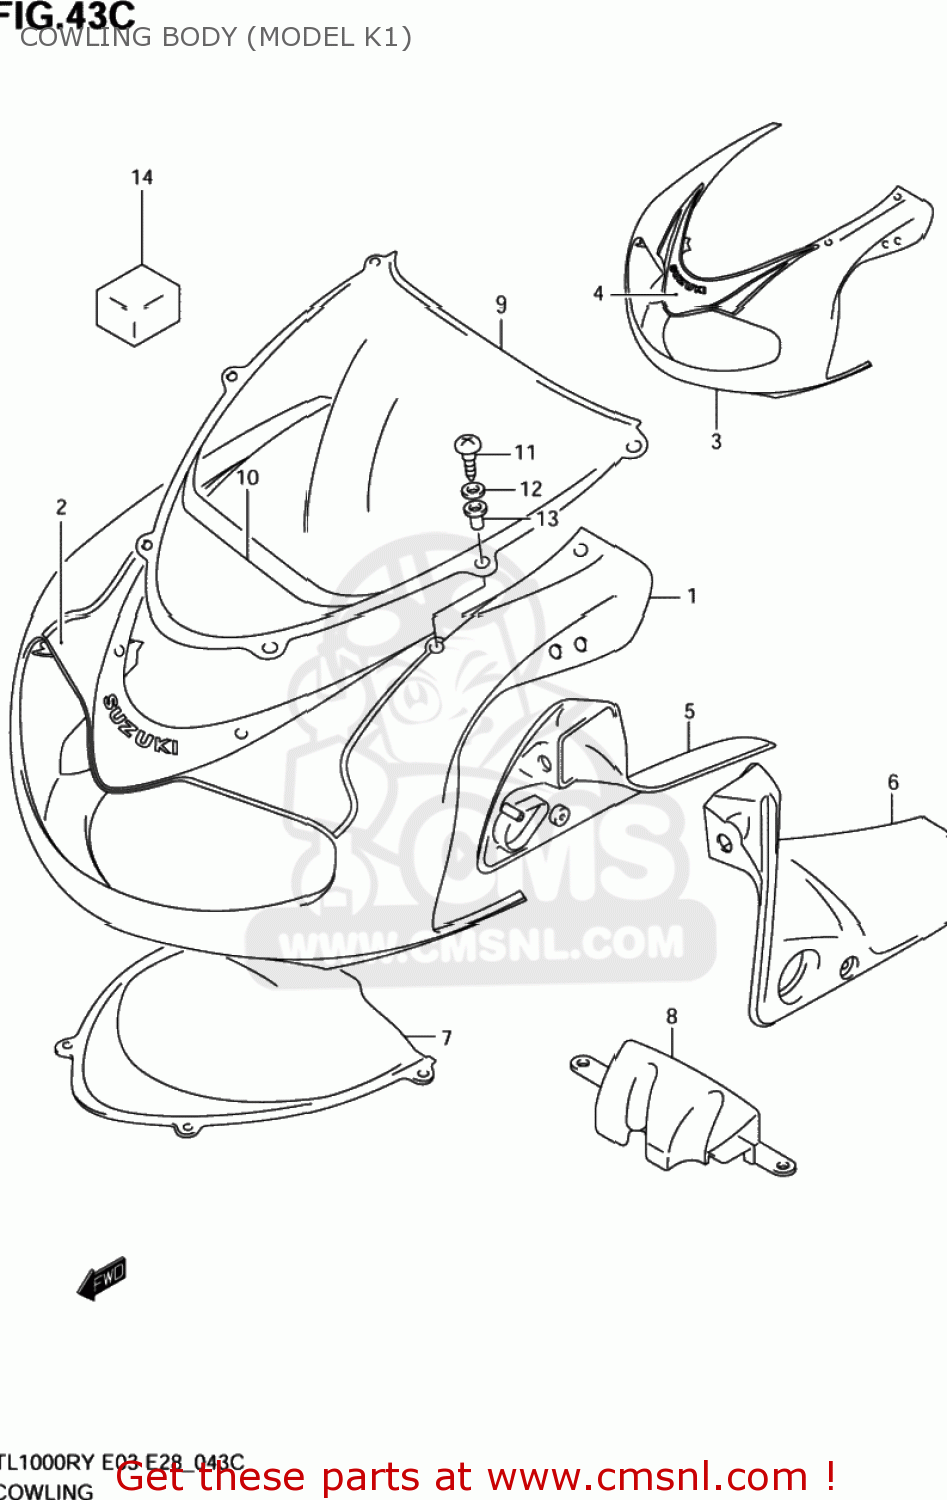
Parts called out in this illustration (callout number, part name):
1	COWLING ASSY,BODY
2	TAPE,FR
3	COWLING ASSY,BODY
4	TAPE,FR
5	PANEL,SIDE,R(BLACK)
6	PANEL,SIDE,L(BLACK)
7	COVER,BODY COWLING
8	COVER,COWLING FR LWR
9	WINDSCREEN
10	TAPE,WINDSCREEN
11	SCREW(5X14)
12	WASHER
13	NUT
14	CUSHION,BODY COWLING
